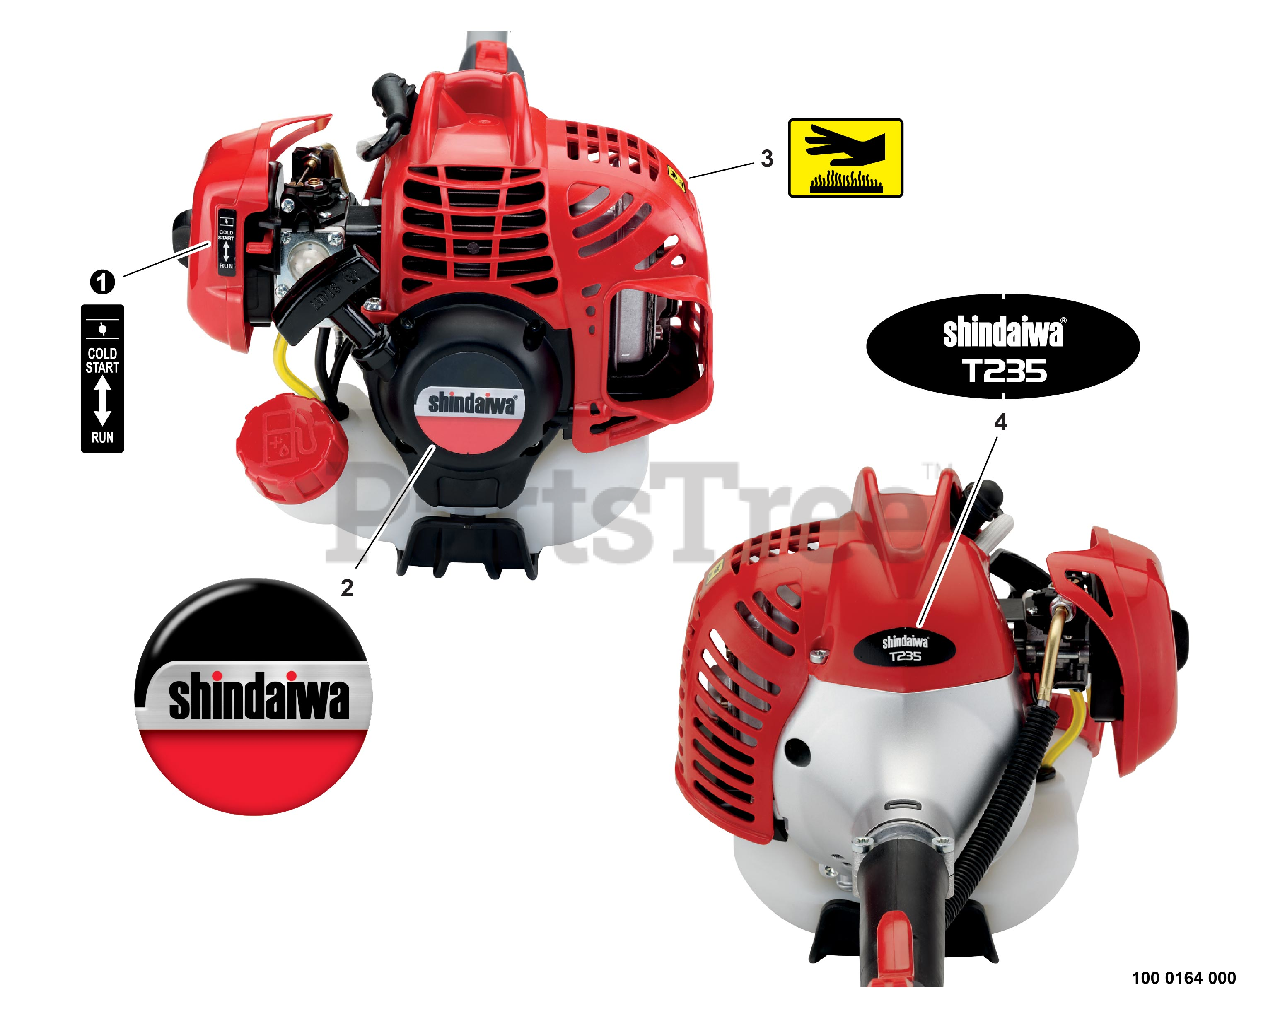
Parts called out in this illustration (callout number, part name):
1	LABEL - CHOKE
2	LABEL - SHINDAIWA
3	LABEL - HOT SURFACE
4	LABEL - MODEL T235
